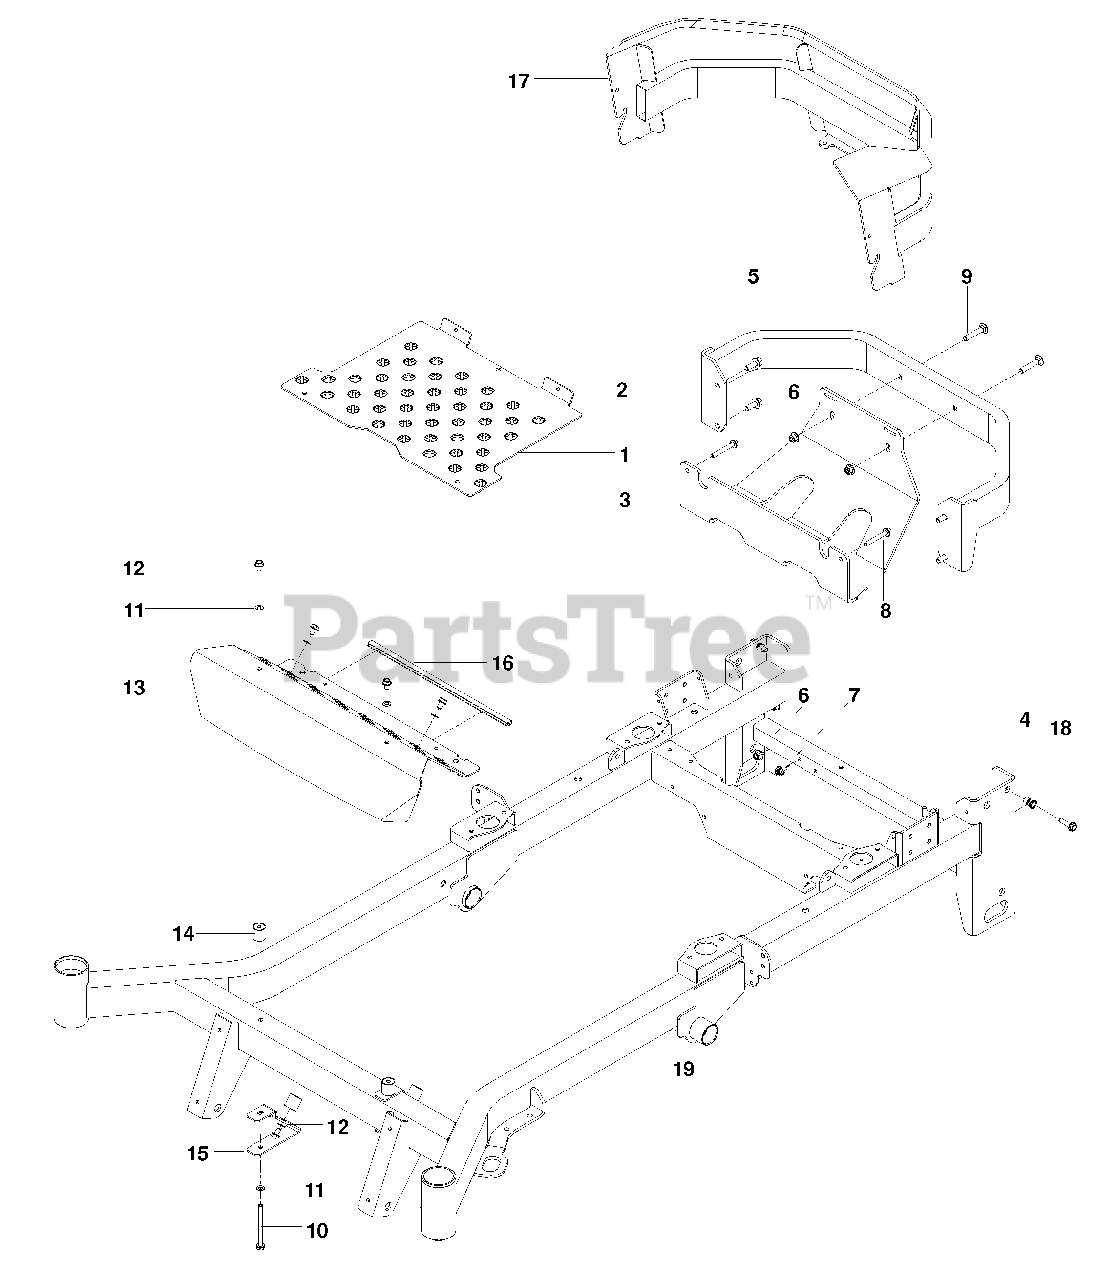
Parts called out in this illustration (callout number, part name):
2	Bolt 7/16-20 X 1 1/2 Hex Nyl
3	Plate, Skid
4	Nutsert 5/16-18
5	Screw 3/8-16 X 1 Hex Flg
6	Nut 3/8-16 Hex Flg Nyloc
7	Nut 5/16-18 Hex Flg Nyloc
8	Screw 5/16-18 X 2 1/4 Hex Flg
9	Bolt 3/8-16 X 2 Rd Hd
10	Screw 5/16-18 X 3 3/4 Hex Flg
11	Washer 5/16 Disc Spring
12	Screw 5/16-18 X 1/2 Slf Tap
14	Mount, F/F Insert
15	Bracket, Rest Mount
16	Flex Trim
17	Guard, Rear
18	Screw 5/16-18 X 1 1/4 Tpblt
19	Frame W/ Safety Decals
